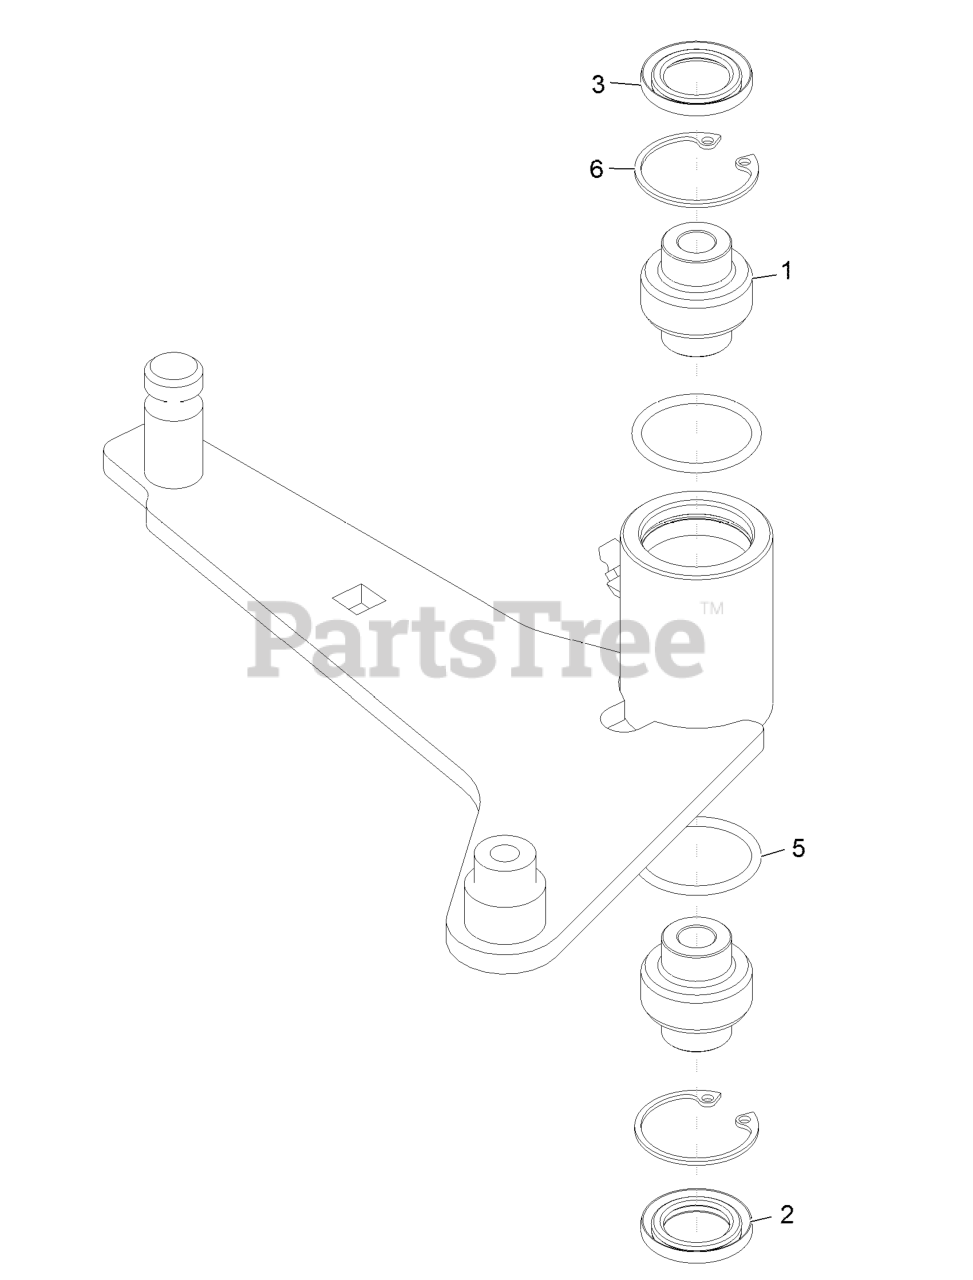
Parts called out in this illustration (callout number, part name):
1	BEARING-SPHERICAL
2	SEAL-LIP, DOUBLE
3	SEAL-LIP, SINGLE
6	RING-SNAP
